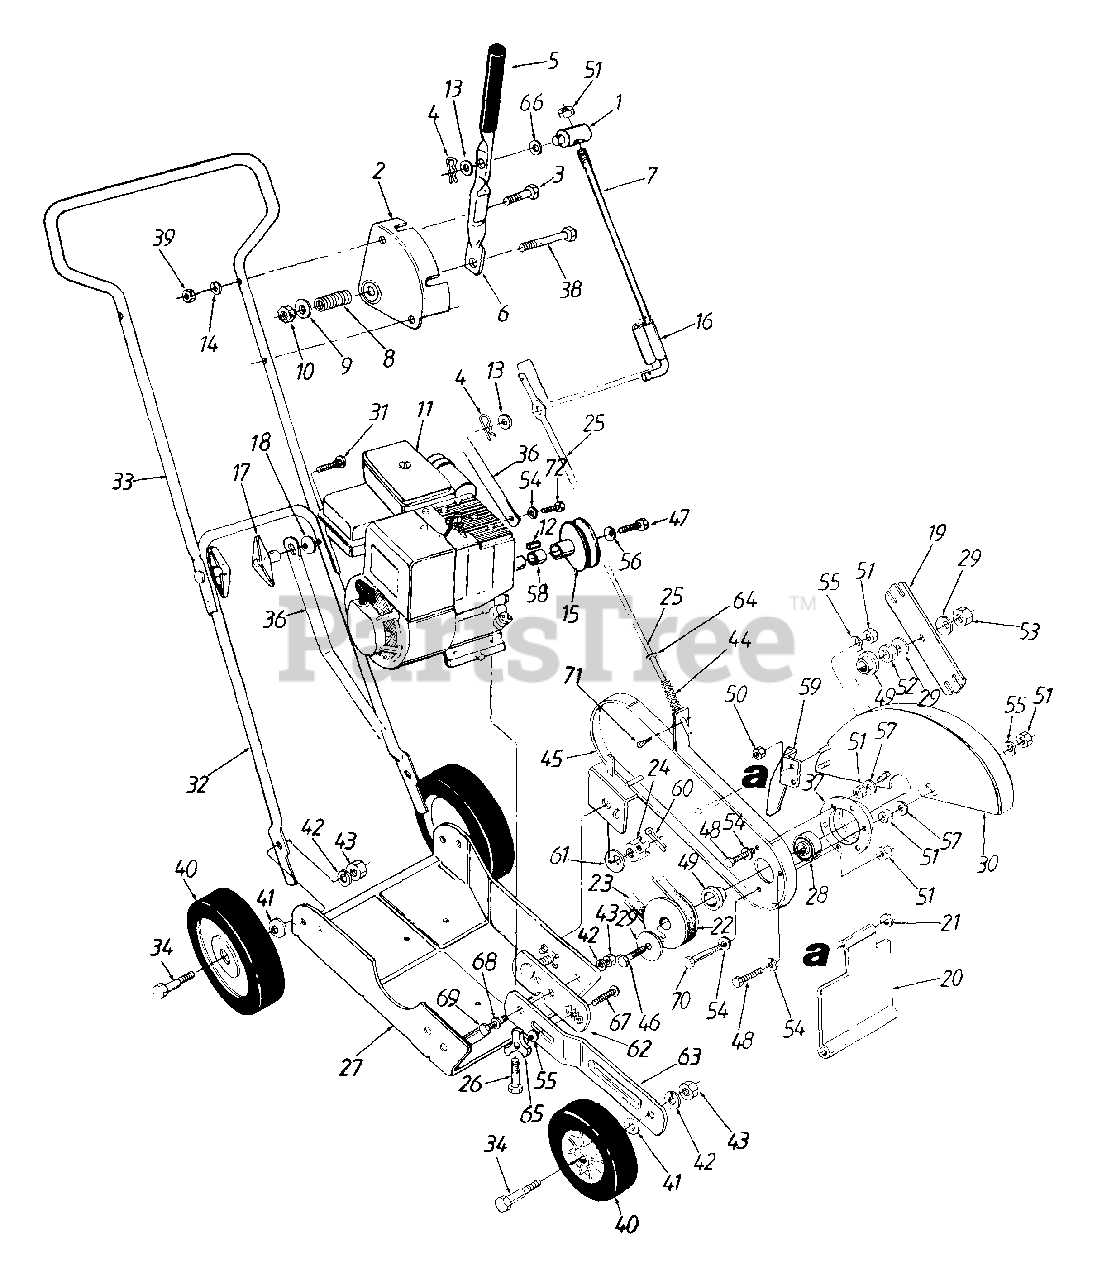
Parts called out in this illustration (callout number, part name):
1	Ferrule
4	Hairpin Clip
5	Foam Grip
6	Engagement Handle
7	Upper Clutch Rod
8	Compression Spring 1.38" Lg.
9	Fl-Wash. .344" I.D.
10	Hex L-Nut 5/16-18 Thd.
11	Engine
12	Sq. Key 3/16" x 1" Lg.
13	Fl-Wash. .344" I.D.
14	L-Wash. 1/4" I.D.
15	Engine Pulley
16	Clutch Rod Lock
17	Wing Nut Ass'y.
18	Saddle Wash. .32" I.D. x .937" O.D.
20	Edger Guide Flap
21	Push Cap
22	3/8" "V"-Pulley
23	V-Belt
24	Hex Slotted Nut 1/2-20 Thd.
25	Lower Clutch Rod
26	Hex L-Wash. TT-Tap Scr. 3/8-16 x 1" Lg.
29	Bell-Wash. 5/8" I.D. x 1-1/4" O.D.
32	Lower Handle
33	Upper Handle
34	Shld. Bolt 3/8-16 Thd.
36	Strut 15.91" Lg.
37	Bearing Housing
38	Hex Bolt 5/16-18 x 2" Lg.
39	Hex Nut 1/4-20 Thd.
40	Wheel Ass'y.
41	Bell-Wash. .38" I.D. x .88" O.D.
42	L-Wash. 3/8" I.D.
43	Hex Nut 3/8-16 Thd.
44	Comp. Spring 2" Lg.
47	Hex Bolt 3/8-24 x 1.5" Lg. (Gr. 5)
48	Hex Cap Bolt 5/16-18 x 1-1/4" Lg.
49	Shld. Spacer .626" I.D.
50	Hex Patch L-Nut 1/4-20 Thd.
51	Hex Nut 5/16-18 Thd.
52	Hex Jam Nut 5/8-18 Thd.
53	Hex Ins. L-Nut 5/8-18 Thd.
54	L-Wash. 5/16" I.D.
55	Bell-Wash. .345" I.D. x .88" O.D.
56	Bell-Wash. .396" I.D. x 1.14" O.D.
57	Fl-Wash. .312" I.D. x .75" O.D.
58	Spacer.748" I.D. x .985" O.D.
61	Bell-Wash. .515" I.D. x 1.14" O.D.
65	Hand Knob
66	Spring Wash. .32" I.D.
67	Carr. Bolt 5/16-18 x 1" Lg. (Special)
68	Spacer .383" I.D. x .503" O.D.
69	Hex Bolt 3/8-16 x 1" Lg.
70	Shld. Bolt 5/16-18 x 1.27" Lg.
71	Cotter Pin 1/8" Dia. x 1" Lg.
72	Hex Bolt 5/16-24 x .62" Lg.
